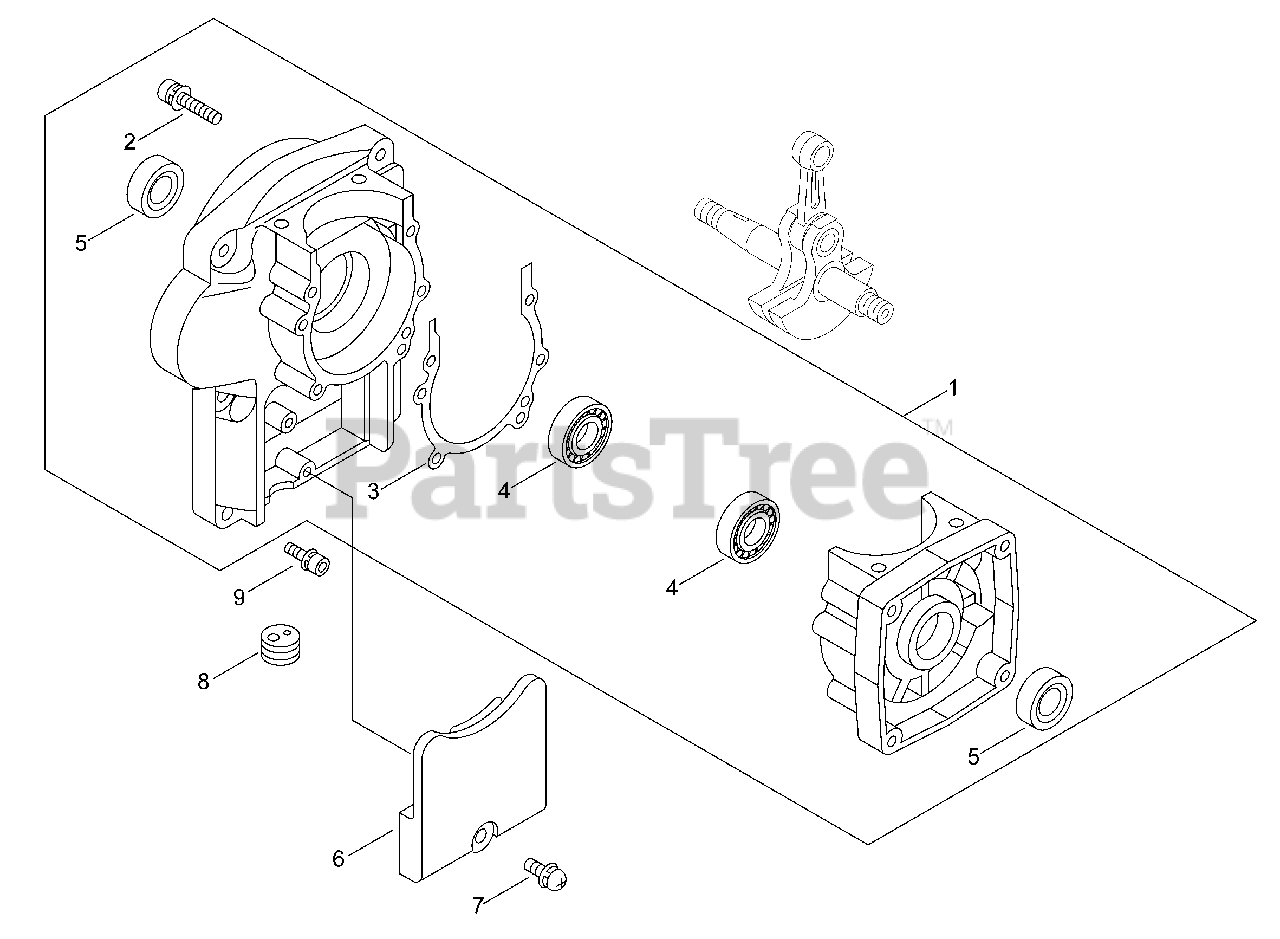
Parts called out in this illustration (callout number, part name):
1	CRANKCASE KIT
2	+SCREW 5×40
3	+GASKET, CRANKCASE
4	+BEARING, BALL 6202
5	+SEAL, OIL
6	COVER, DUST
7	SCREW 5×18
